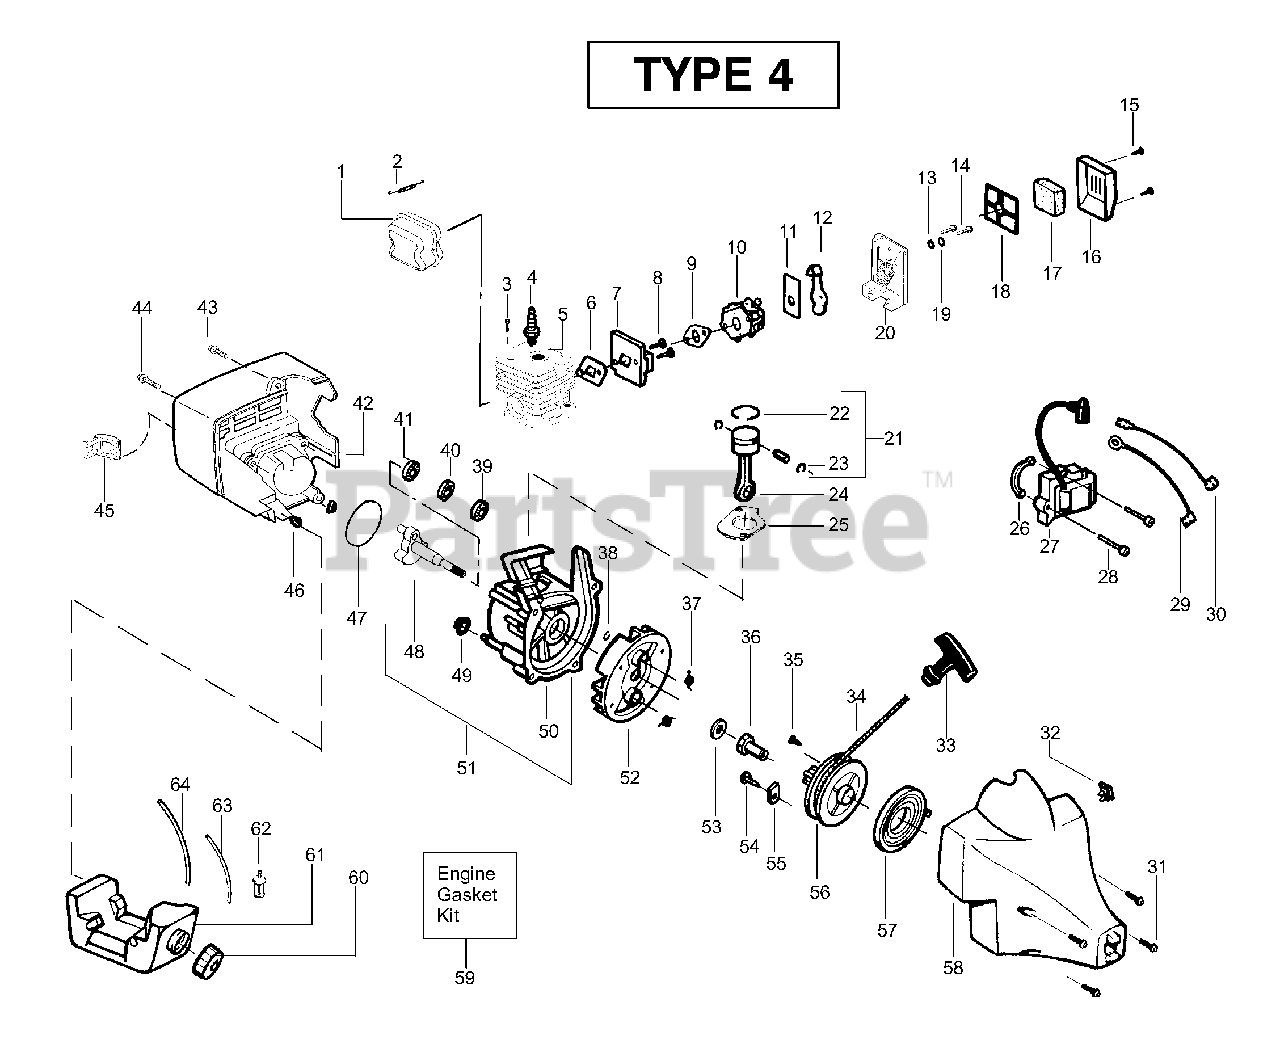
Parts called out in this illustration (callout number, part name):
1	Kit - Muffler
2	Muffler Spring
3	Screw-Cylinder
4	Spark Plug (RCJ 6Y)
5	Kit - Cylinder
6	Gasket-Cyl/Carb.(kit)
7	Adaptor-carb.
9	Gasket-Carb.(kit)
10	Kit - Carburetor Ass'y
11	Plate-Choke Mounting
12	Lever-Choke
16	Cover-Air Box
17	Foam-Air Filter
18	Plate-Air Filter Support
19	Spacer-Choke
21	Kit - Piston
22	Piston Ring
23	Retainer-Piston Pin
24	Assy-Connecting Rod
25	Gasket-Cylinder(kit)
26	Spacer-Module
27	Ignition Module
29	Assy-Ground Wire
30	Assy-Leadwire
31	Screw
32	Kit-Switch
33	Handle-Starter
34	Kit - Rope
36	Coupling-Drive
37	Spring-Starter Dog
38	Retain. Ring-C'shaft
39	Bearing-Outer
40	Kit-Seal-C'case
41	Bearing-Inner
44	Screw
45	Guard-Muffler
46	Isolator-Shroud
47	O-Ring-C'case(kit)
48	Assy-Crankshaft
49	Isolator-Crankcase
50	Assy-Crankcase
51	Assy-C'case & C'shaft
52	Assy-Flywheel
53	Washer-Flat
55	Retainer-Can
56	Kit-Starter Pulley
57	Spring-Starter
58	Assy-Fan Housing
59	Kit-Engine Gasket
60	Assy-Fuel Cap
61	Assy-Fuel Tank
62	Assy-Fuel Pickup
63	Kit-Fuel Line
64	Kit-Fuel Line
